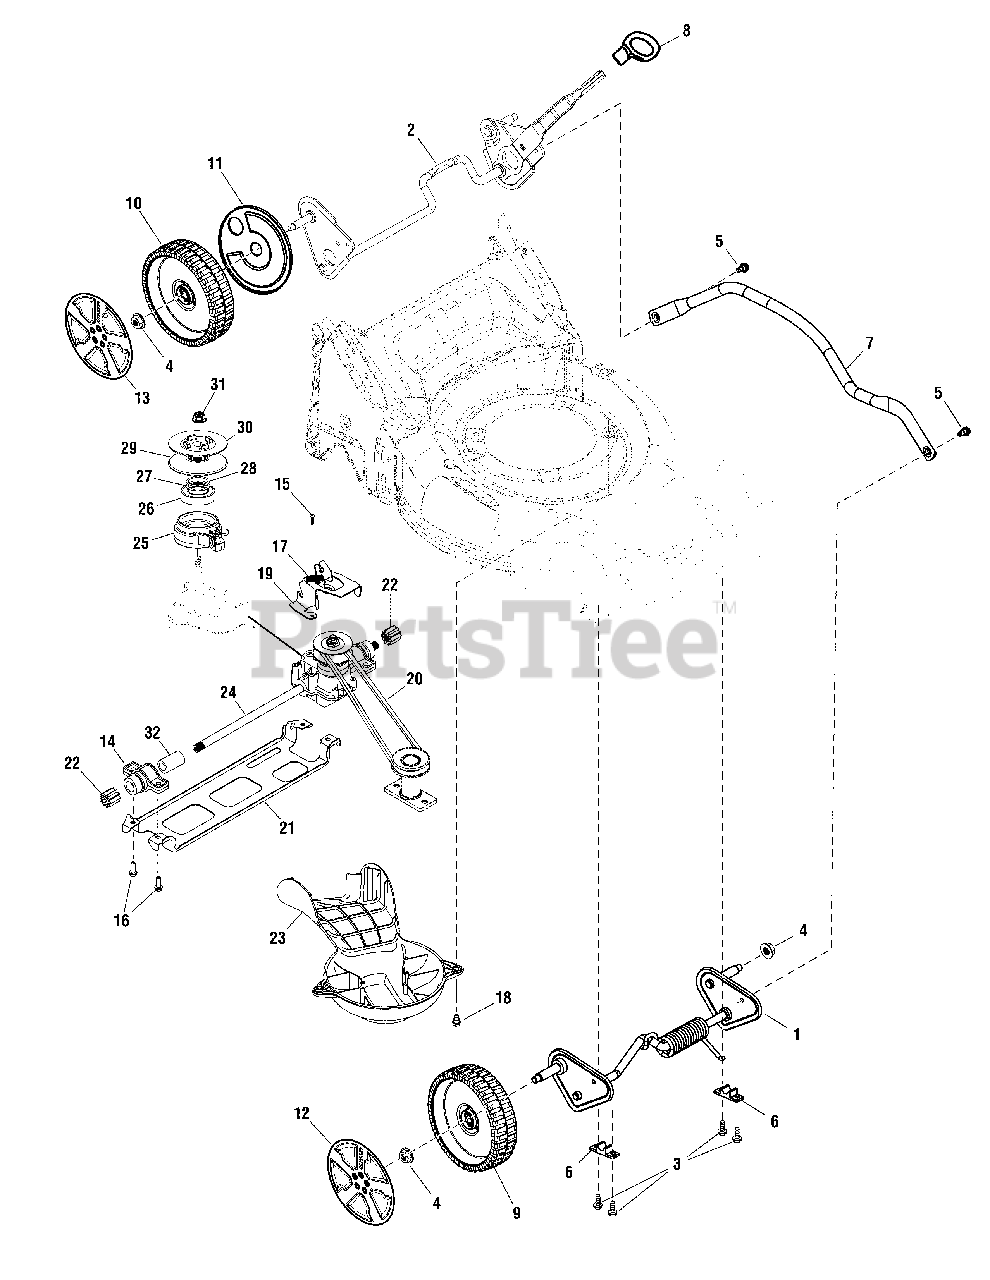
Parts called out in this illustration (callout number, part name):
1	AXLE, Front
2	AXLE, Rear
3	SCREW, 1/4-15X3/4, Self-Tapping, BZ
4	NUT, Hex Flange, Nylock, 3/8-16
5	SCREW, 1/4-20 x 1/2
6	BUSHING, Lock
8	KNOB, Red
9	WHEEL, 180 x 47
10	WHEEL, Drive
11	DUST COVER, Wheel
12	HUBCAP, Front
13	HUBCAP, Rear
14	BEARING ASSEMBLY
15	SCREW, Hex Washer Head, .159 x .43
16	SCREW, 1/4-15 x 1-1/4
18	SCREW, 1/4-20 x 1/2
19	BRACKET
21	SUPPORT
22	GEAR, 9 Tooth
23	COVER, Rear
24	TRANSMISSION
25	CAM PULLEY, Speed
26	BEARING, Ball
29	PULLEY HALF, Lower
30	PULLYE HALF, Upper
31	NUT, Lock
